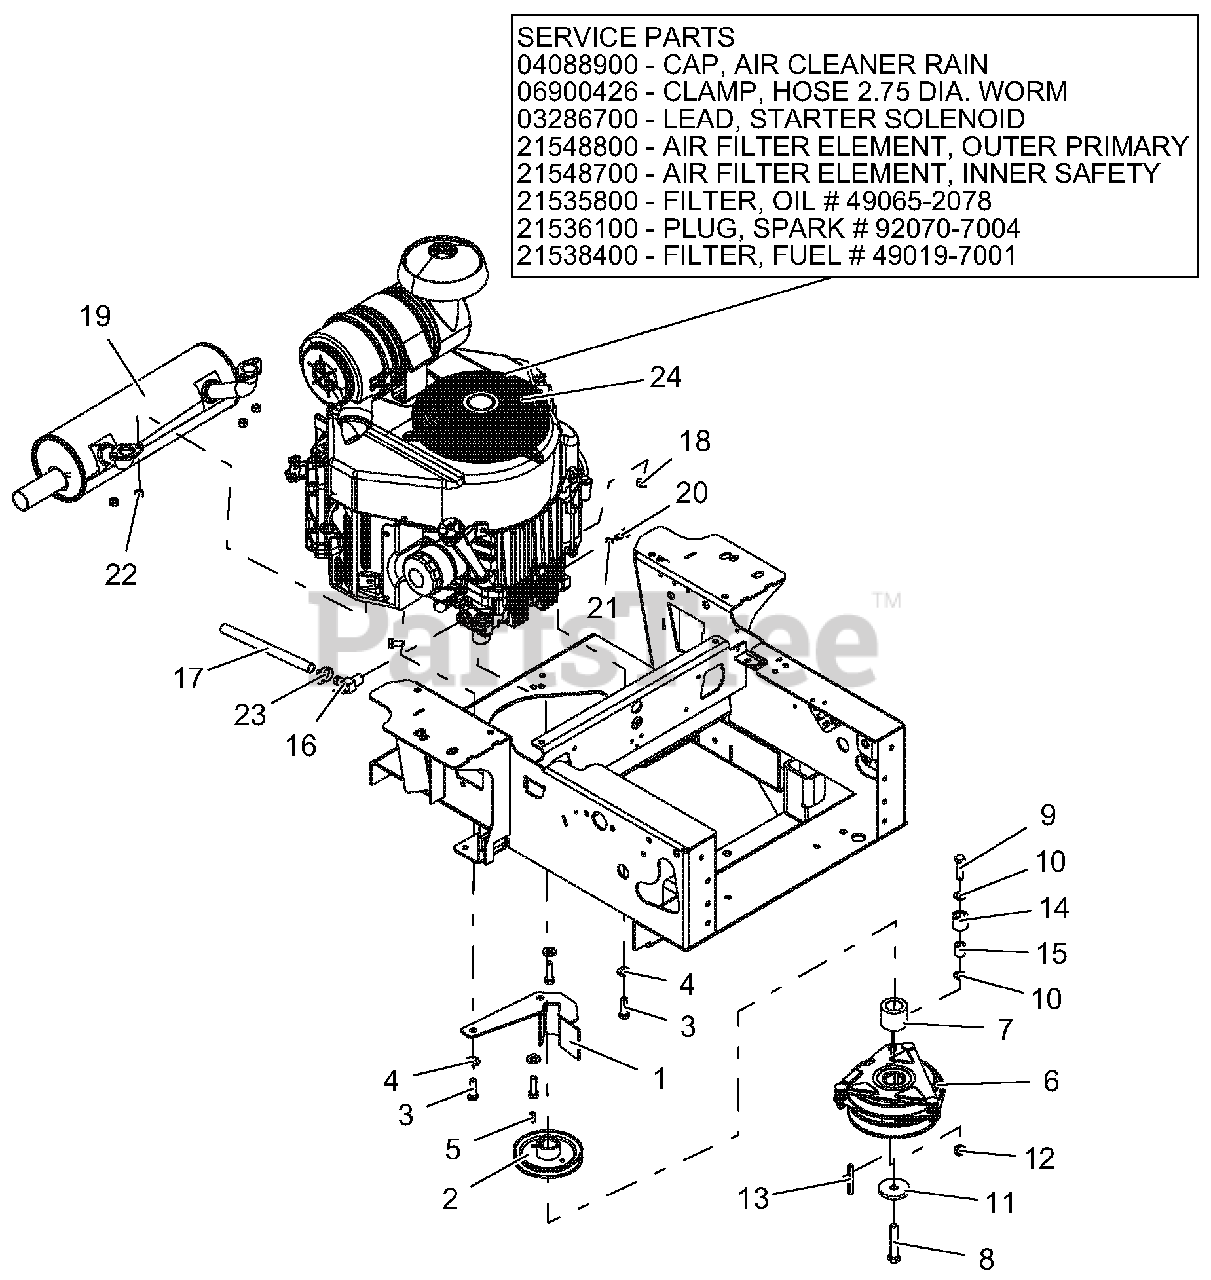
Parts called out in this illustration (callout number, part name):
1	WMT, 100I CLUTCH STOP - BLK
2	PULLEY, 4.50 OD X 1.127 ENGINE-BLACK
3	BLT-HEX .38-16X1.25 GR5 YWZC NYTORQ
4	WSHR, 3/8" SPRING DISC
5	KEY-SQ .250X.250X.625
6	CLUTCH, OGURA GT2.5-FE02
7	SPACER, 1.125 X 1.75 X 1.40
8	BLT-HEX .44-20X2.50 GR5 EP80 YWZC
9	BLT-HEX .38-16X1.50 GR5 YWZC
10	WSHR-FL-STL.406X.812X.065 YWZ
11	WSHR-FL-STL .469X2.00X.25 YWZC
12	NUT, LK-TOP-FLG .38-16 YWZC
13	KEY, .25X.25X2.25
14	BUMPER, RUBBER .62 X 1.0 X .88 LG
15	BUSHING, SLV .407X.625X.813
16	DRAIN, 1/2" OIL
17	TUBE, OIL DRAIN 8" CLEAR VINYL
18	CLAMP, FUEL LINE
19	MUFFLER, KAWASAKI FX24/26 HP
20	@BLT-HEX M8-1.25X20 YWZC
21	WSHR-LK .31X.078 REG YWZC
22	NUT-LK-TOP M8-1.25 YWZC
23	CLAMP, .88 DIA HOSE
24	ENGINE, KAWASAKI FX730
